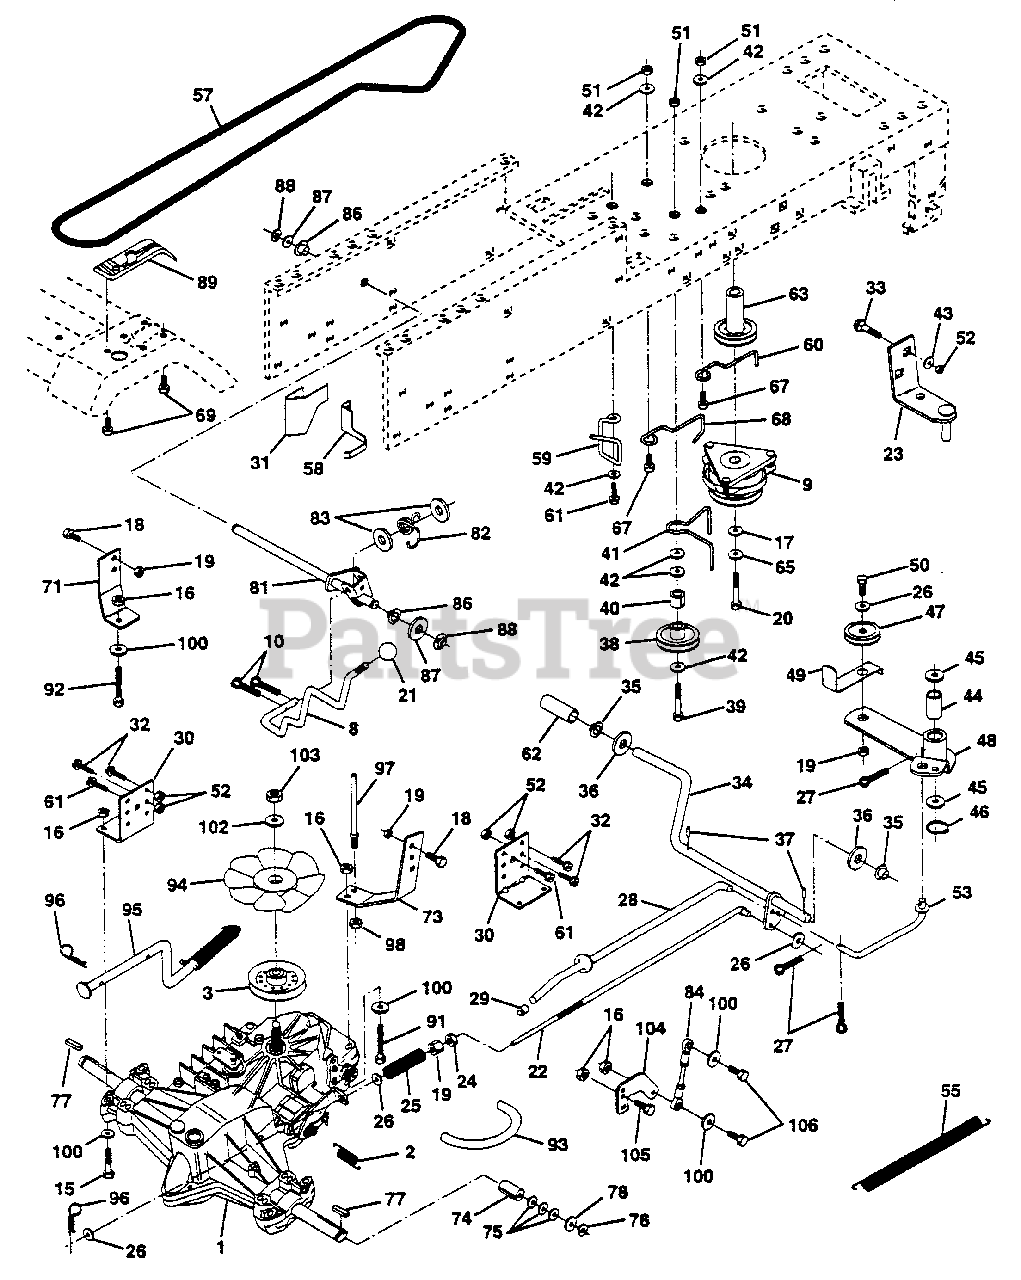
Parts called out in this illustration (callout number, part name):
1	Transaxle Assembly
2	Spring, Return, Brake
3	Pulley, Transaxle
8	Rod Shift Fender YT
9	Clutch, Electric
10	Pin Cotter 1/8 x 1 CAD
15	Bolt Fin Hex 5/16-18 Unc
16	Nut Lock Hex W/Ins. 5/16-18 Unc P
17	Washer 1-1/2 OD x 15/32 ID x .250
18	Bolt Fin Hex 3/8-16 Unc x 1 Gr. 5
19	Nut Lock Hex W/Wsh 3/8-16 Unc
20	Bolt, Hex
21	Knob, Duckhead 1/2-13
22	Rod, Brake Hydro
23	Bracket, Asm Mtg Clutch
24	Nut
25	Spring, Brake Rod
26	Washer
28	Rod, Parking Brake
29	Cap, Parking Brake
30	Bracket, Transaxle
31	Keeper Belt Lh
32	Bolt Hex Hd 5/16-18 Unc x 3/4
33	Bolt Carriage 5/16-18
34	Shaft, Foot Pedal
35	Bearing, Nylon
37	Pin, Roll
38	Pulley, Idler, Flat
40	Spacer, Split
41	Keeper, Belt Retainer
42	Washer 13/32 x 13/16 x 12 Gauge
43	Washer 11/32 x 5/8 x 12 Ga.
44	Bearing, Nylon
45	Washer, Hardened
46	Ring, Klip
47	Pulley, Idler, V-Groove
48	Bellcrank Assembly
49	Retainer, Belt
50	Bolt
52	Nut, Crownlock 5/16-18
53	Link, Clutch
55	Spring, Return, Clutch
57	V-Belt, Ground Drive
58	Keeper Belt
59	Keeper, Center Span
60	Keeper Belt Engine
61	Screw, Thdroll. 3/8-16 x 1 Type TT
62	Cover, Pedal
63	Pulley, Engine
65	Washer
67	Bolt
68	Keeper Belt Engine
69	Screw Hex Wsh Hi-Lo 1/4-1/2 UNC
71	Strap Torque Lh Hydro 18/20" T
73	Strap Torque Rh Hydro 18/20" T
74	Spacer, Split
75	Washer 25/32 x 1-1/4 x 16 Gauge
77	Key, Square
78	Washer 25/32 x 1-5/8 x 16 Gauge
81	Shaft Asm. Cross Hydro 20" Tires
82	Spring Torsion T/A
83	Washer 17/32 x 3/4 x 16 Ga.
84	Rod, Tie Hydro 20" Tires
86	Bushing Rod Steering 629/632 ID
87	Washer 21/32 x 1-1/4 x 16 Ga.
88	Ring Klip #5304-62
89	Console, Shift
91	Bolt Fin Hex 5/16-18 x 2-1/4
92	Soft Fin Hex 5/6-18 Unc x 1-1/2
93	Line Fuel Hydro 4"
94	Fan, Hydro 7"
95	Control Bypass Hydro 18" Tires
96	Retainer Spring 1" Zinc/Cad
97	Keeper Belt Rh Hydro 0750. 18/20"
98	Nut Keps Hex 3/8-16 Unc
100	Washer 11/32 x 3/4 x 16 Ga.
102	Washer Belleville .501D x 1.50D
103	Nut Nylon Insert 1/2-20 Unf.
104	Arm, Control Hydro
105	Screw Cap Hex 5/16 x 18 x 1
106	Bolt Fin Hex 5/16-18 Unc x 1-1/4
